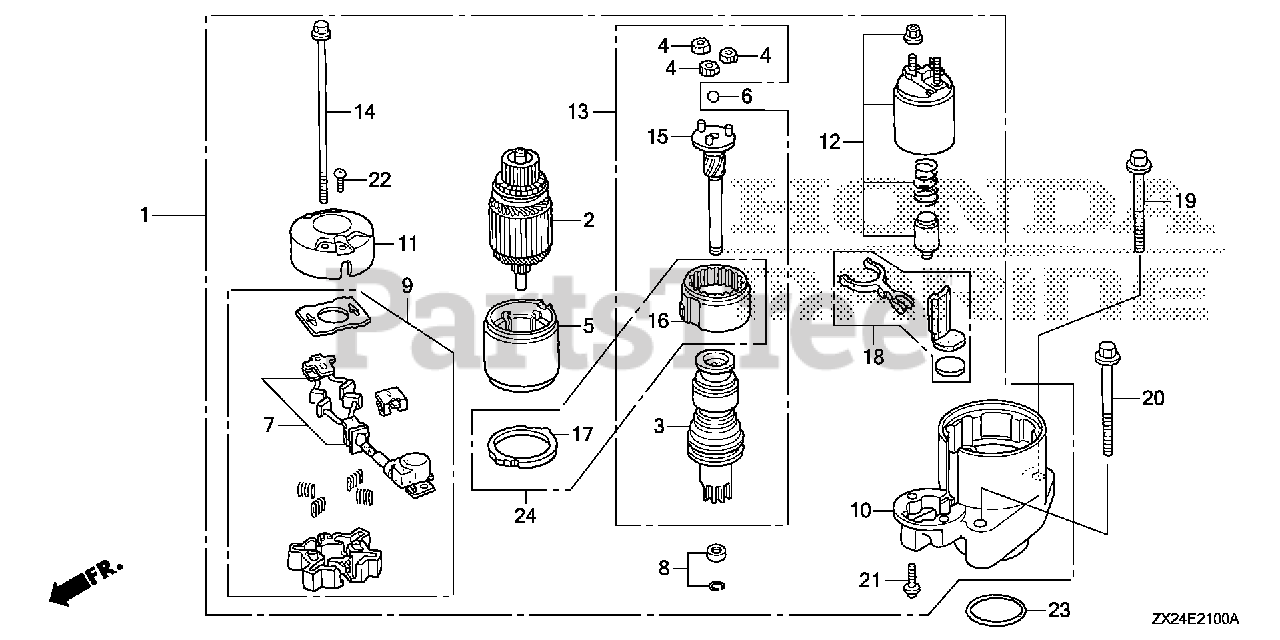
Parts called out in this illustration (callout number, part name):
1	STARTER MOTOR ASSY.
3	CLUTCH, OVERRUNNING
4	GEAR ASSY., PLANETARY
6	BALL, STEEL
8	STOPPER SET, SLEEVE
9	HOLDER, BRUSH
10	BRACKET, FR.
11	BRACKET, RR.
12	SWITCH ASSY., MAGNET
13	SHAFT ASSY., CLUTCH
14	BOLT A, THROUGH
15	SHAFT ASSY., GEAR
19	BOLT, FLANGE (10X90)
20	BOLT, FLANGE (10X110)
21	SCREW, PAN (6X22)
22	SCREW, PAN (5X8)
23	O-RING (59.4X3.1)
24	GEAR ASSY. (INNER)
